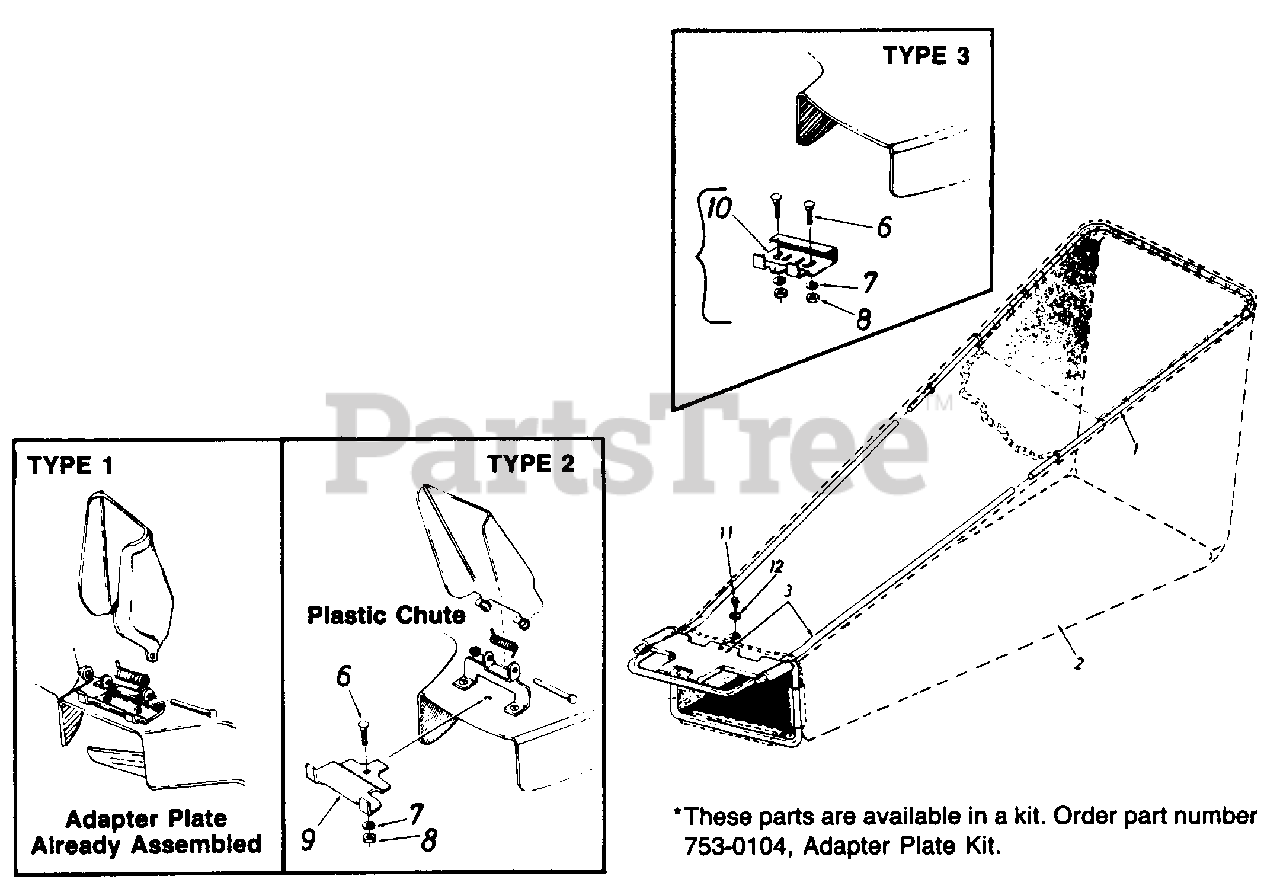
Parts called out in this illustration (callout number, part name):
1	FRAME-UPPER
2	BAG-GRASS
3	FRAME-LOWER
6	BOLT-CARRIAGE 1/4-20 X .50
7	LOCK WASHER 1/4 DIA
8	NUT-HEX 1/4-20
9	PLATE-ADAPTER
10	PLATE-ADAPTER
11	SCREW-HEX WASH SF TAPP
12	WASHER-SPRING BELL
